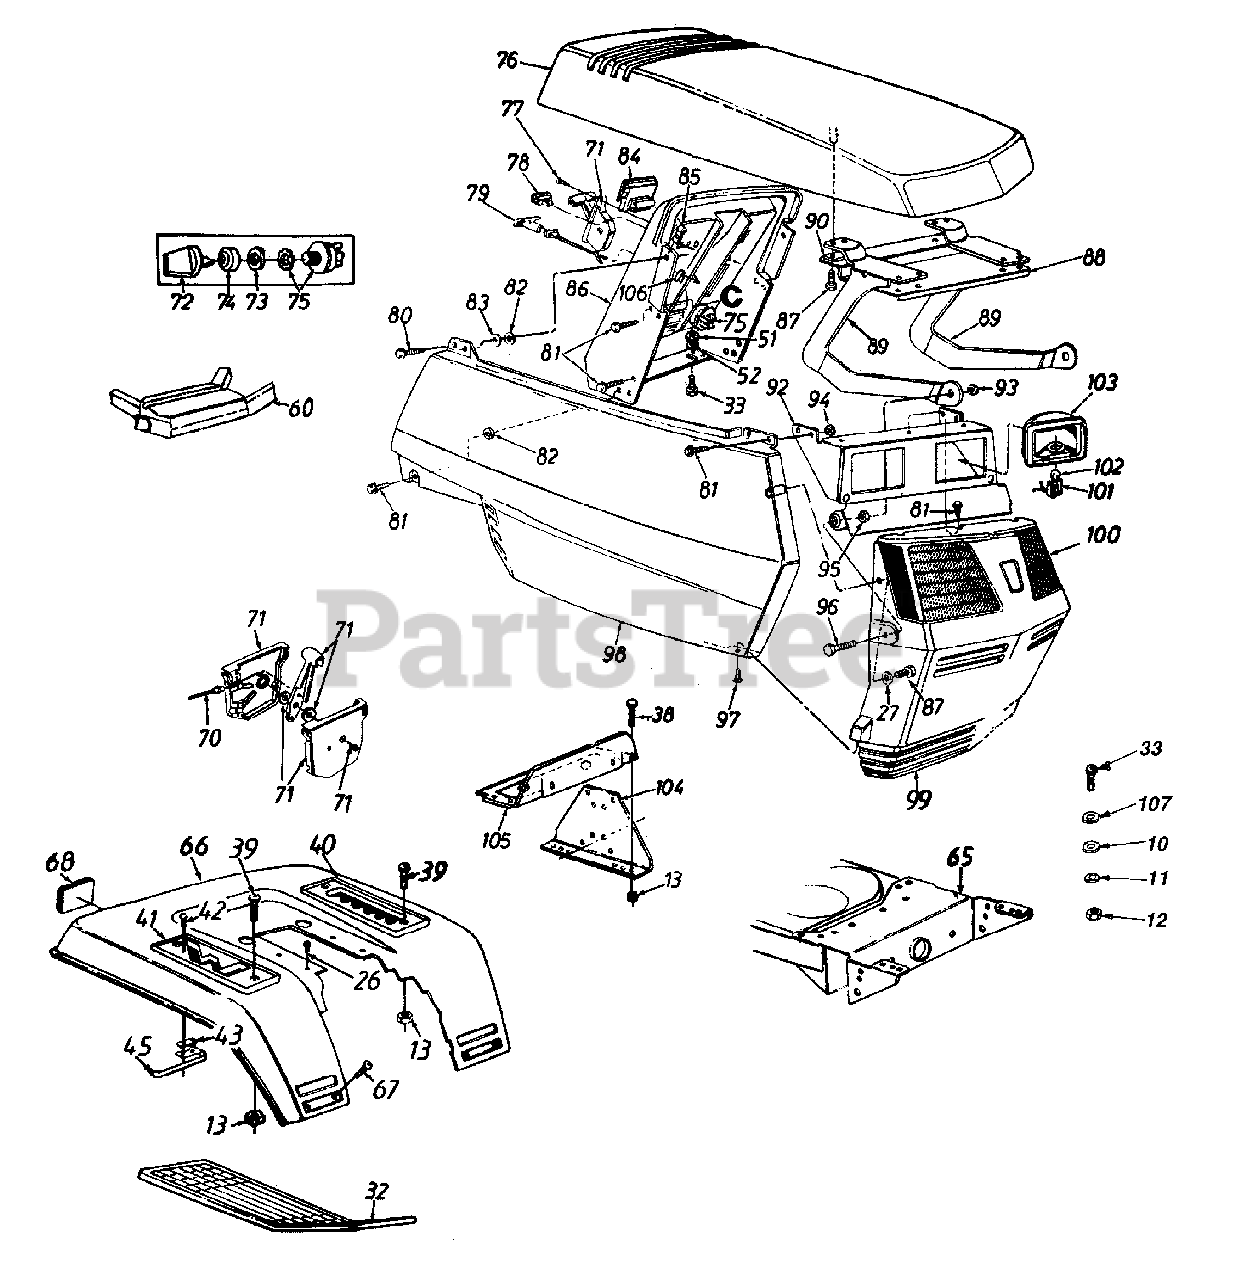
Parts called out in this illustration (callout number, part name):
10	Speed Nut
11	L-Wash. 5/16" I.D.
12	Hex Nut 5/16-18 Thd.
13	Hex Sems Nut 1/4-20 Thd.
26	Hex Wash. Hd. AB-Tap Scr.5/16 x .75" Lg.
27	Fl-Wash. .218" I.D. x .5" O.D.
32	Rubber Foot Pad-L.H.
33	Hex Bolt 5/16-18 x .75" Lg.
38	Hex Bolt 1/4-20 x .62" Lg.
39	Truss Mach. Scr. 1/4-20 x .75" Lg.
40	7-Speed Index Brkt.
41	Forward/Reverse Index Brkt.
42	Hex Wash. Hd. AB-Tap Scr. #8 x .5" Lg.
43	Insulator Nut Plate
45	Reverse Safety Switch
51	Hex Sems Nut 5/16-18 Thd.
52	Fl-Wash. .343" I.D. x .687"
60	Steering Wheel Insert
68	Reflector
70	Throttle Wire 28" Lg.
71	Throttle Control Box Ass'y.
72	Ignition Key
73	Ignition Switch Nut
74	Ignition Switch Cap
75	Ignition Switch
76	Hood (Yellow)
77	Truss Mach. AB-Tap Scr. #10 x.5" Lg.
78	Light Switch
79	Choke Control
80	Hex Wash. Hd. Tap Scr.1/4 x .75" Lg.
81	Hex Tap Scr. 1/4-20 x .5" Lg.
82	Push Nut Fastener
83	Fl-Wash. .27" I.D. x .948"
84	Ammeter
85	Speed Nut 1/4-20 Thd.
86	Dash Panel
87	Hex Wash. Hd. B-Tap Scr.1/4 x .62" Lg.
94	Hex L-Nut 1/4-20 Thd.
95	Hex Jam Nut 5/16-18 Thd.
96	Hex Bolt 5/16-18 x 7/8" Lg.
97	Truss Mach. B-Tap Scr.#10 x .5" Lg.
98	Side Cover-R.H. (Yellow)
99	Grille (Yellow)
100	Lens-L.H.
101	Twist Lock-Lamp Socket
102	Lamp
103	Headlight Housing
107	Fl-Wash. .34" I.D. x 1" O.D.
